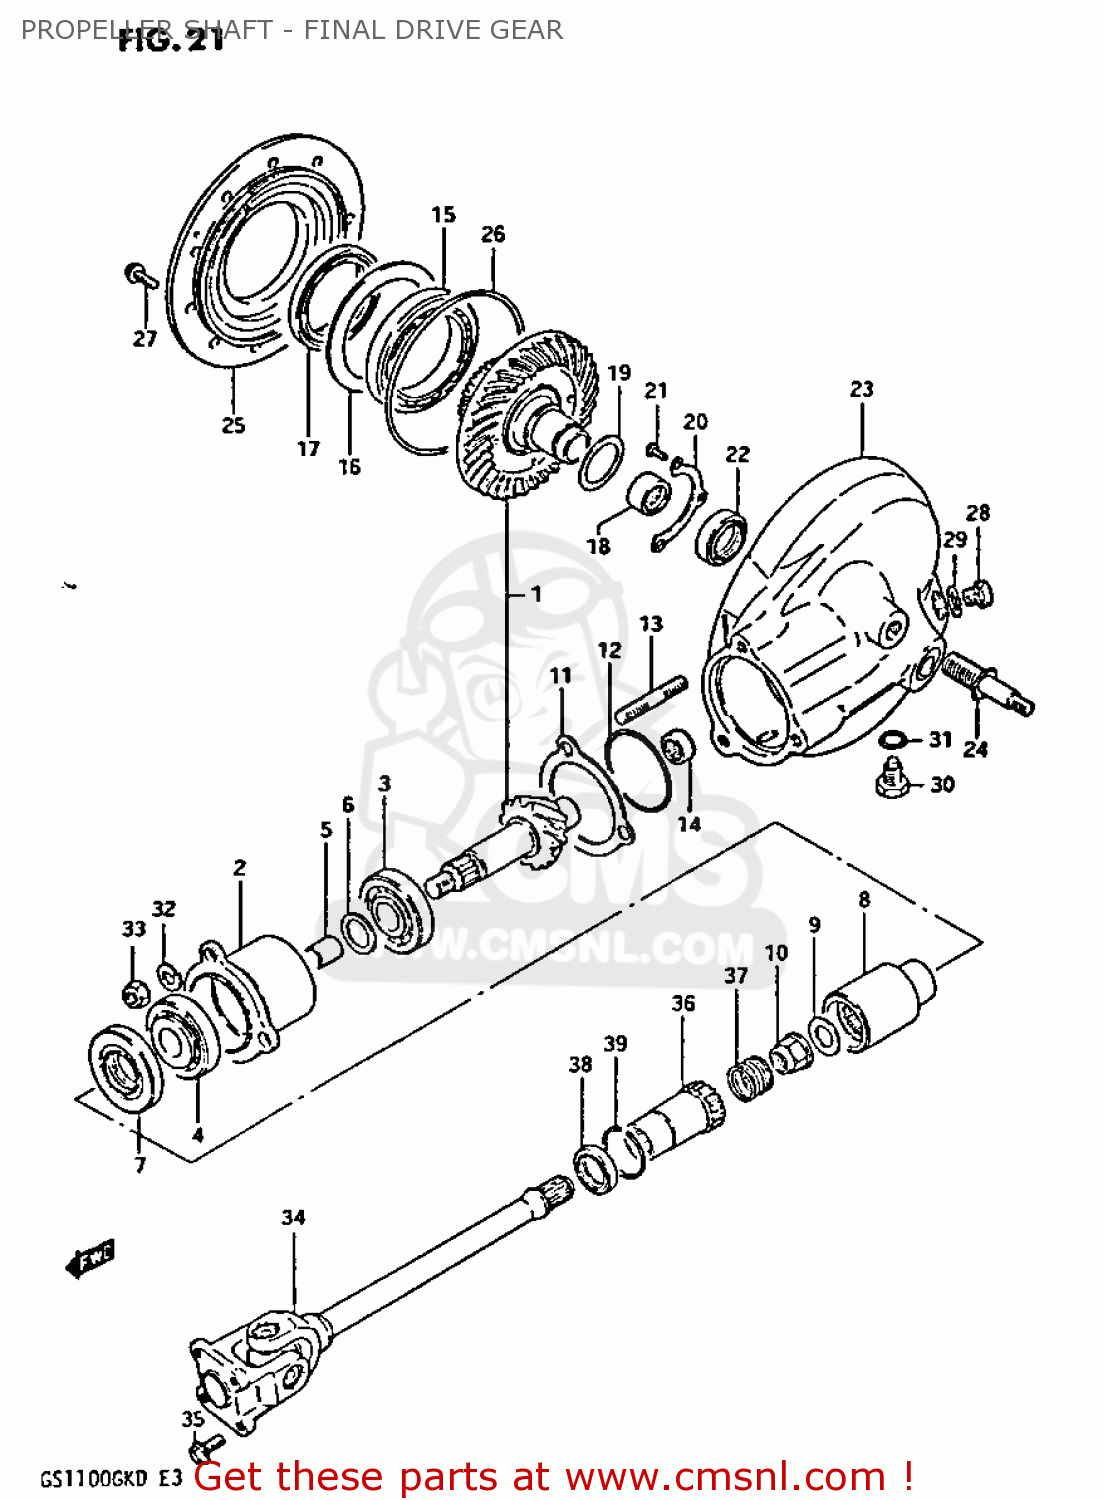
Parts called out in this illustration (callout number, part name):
1	GEAR SET,FINAL BEVEL
2	HOUSING,DRIVE GEAR
3	BEARING(25X52X19.25)
4	BEARING(25X52X16.25)
5	SPACER (25.2X30X3.5)
6	SHIM (25X30X2
7	SEAL,OIL(32X54X7)
8	GEAR,FINAL DRIVE
9	WASHER(14X29X4)
10	NUT
11	SHIM,DRIVE GEAR HOUSING
12	O RING(D:2.4,ID:62.6)
13	STUD 10X30
14	BEARING(24X33X17)
15	BEARING(70X110X13)
16	SHIM,DRIVEN GEAR BEARING
17	SEAL,OIL(70X96X16)
18	BEARING(35X48X23.7)
19	SHIM,FINAL DRIVEN GEAR
20	RETAINER,FINAL DRIVEN GEAR BRG
21	SCREW 6X12
22	SEAL,OIL(30X42X7)
23	CASE ASSEMBLY,FINAL GEAR
24	STUD
25	CASE,FINAL GEAR BEARING
26	O-RING (D:3.1 ID:144.4)
27	BOLT
28	PLUG(14X12)
29	GASKET(14X19.2X2) (NAS)
30	PLUG
31	GASKET(14X19.2X2) (NAS)
32	LOCK WASHER
33	NUT
34	SHAFT ASSEMBLY,PROPELLER
35	BOLT(8X17)
36	COUPLING,PROPELLER SHAFT
37	SPRING
38	SEAL,OIL(30X40.5X5.5)
39	CIRCLIP
